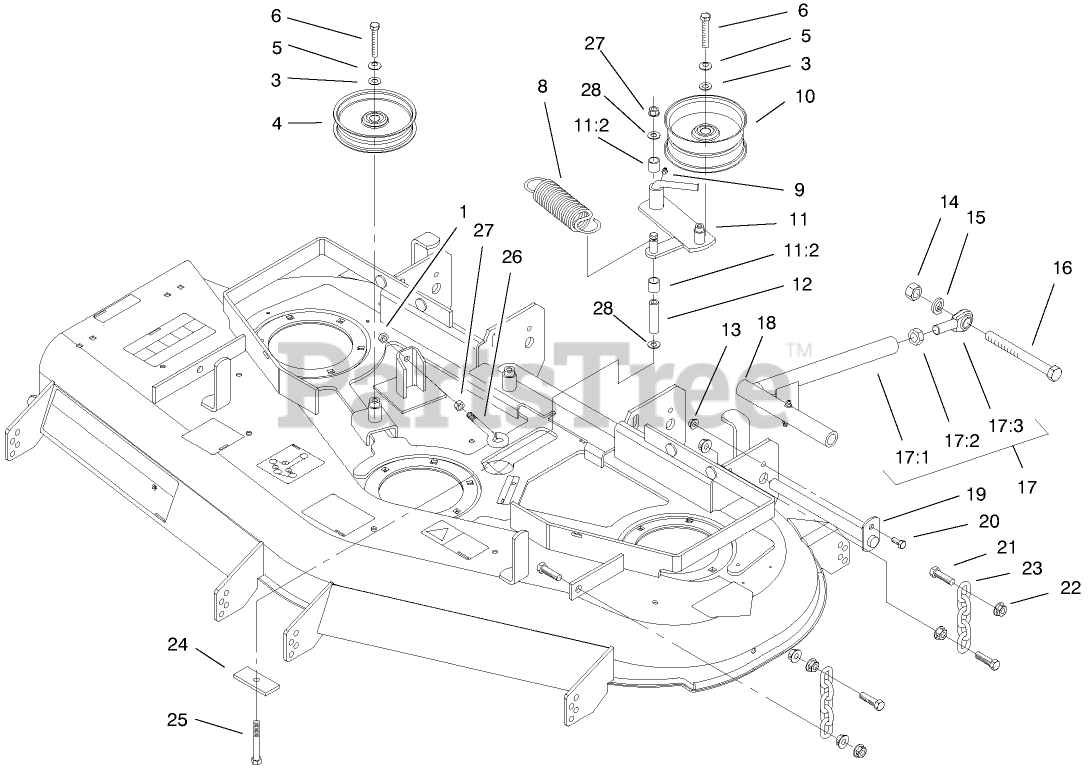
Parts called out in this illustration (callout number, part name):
1	NUT-HEX
3	WASHER-FLAT
4	Pulley-Idler
5	Washer
6	SCREW-HH
8	Spring-Extension
9	Zerk-Grease
10	Pulley
11	IDLER ARM ASM
11:2	Bearing-Pivot
12	Bushing
13	NUT-LOCK NI
14	NUT-HEX
15	WASHER-LOCK
16	Screw-HH
17	Strut ASM
17:1	Strut
17:2	NUT-HEX
17:3	Rod End
18	FITTING-STRAIGHT
19	Pin-Strut
20	SCREW-HH
21	SCREW-HH
22	NUT-HF
23	Chain-Lift
24	PLATE-RETAINER, BOLT
25	Screw-HH
26	BOLT-EYE
27	NUT-LOCK, NI
28	Washer-hardened
